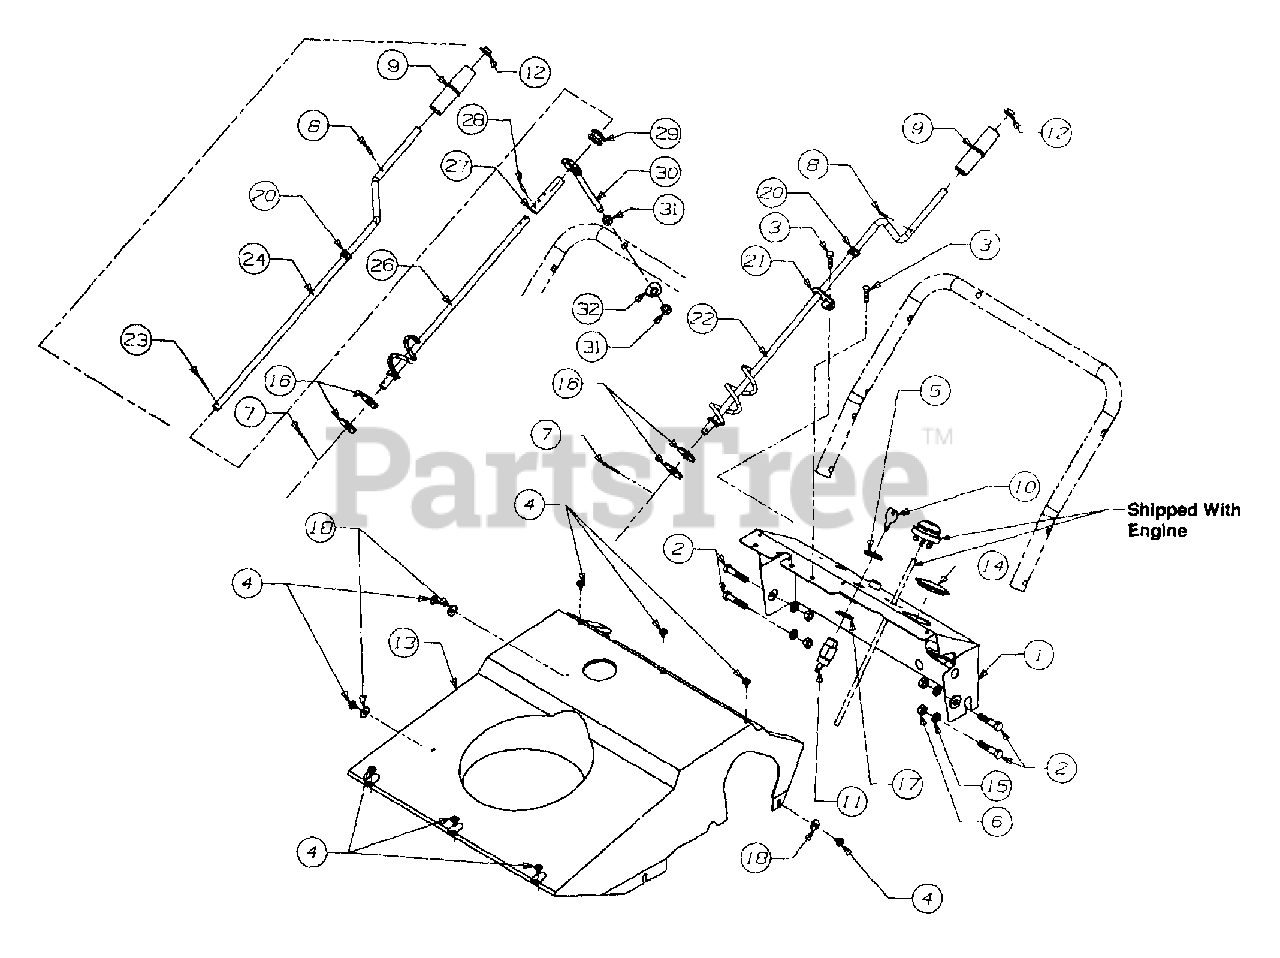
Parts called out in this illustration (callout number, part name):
3	Hex Tap Screw
4	Hex Tap Screw
5	Hex Nut
6	Hex Nut
7	Cotter Pin
9	Chute Crank Knob
10	Key-Ignition
11	Switch-Key
12	Nut Push
13	Shroud
15	Lock Washer
16	Flat Washer
17	Internal Lock Washer
18	Flat Washer
20	Bushing
21	Bracket, Chute Crank
22	Crank Assembly, Chute
23	Cotter Pin
29	Grommet - Rubber
30	Eyebolt - Chute Crank
31	Nut - Hex
32	Washer - Saddle
